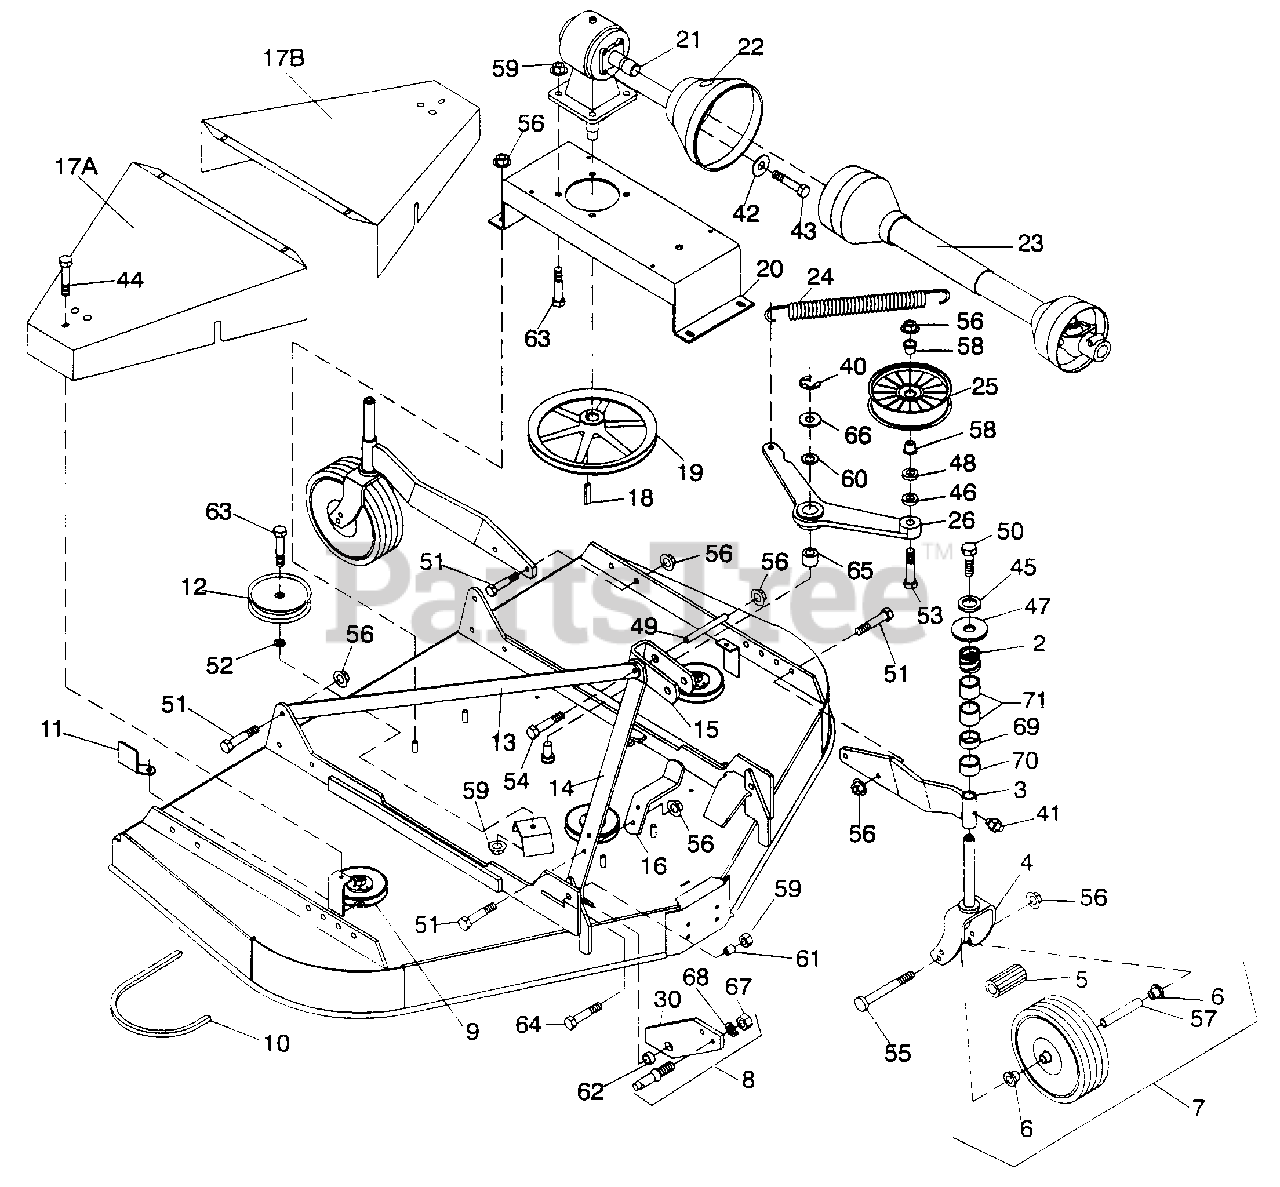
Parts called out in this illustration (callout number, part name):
2	Compression spring
3	Caster arm assembly - Right
3	Caster arm assembly - Left
4	Model 483 Caster shaft and yoke assembly
5	Roller bearing .75 x 1.38 x 1.5
6	3/4 x 1.415 Flanged wheel bearing with groove
7	10" Heavy-duty wheel w/bearing & sleeve
8	Category 1 mounting pin with nut and lockwasher
9	CW Spindle assembly
10	V-Belt
11	Belt guide, 8 GA formed
12	Flat idler, 5.5" Dia.
13	Offset link
14	Offset link
15	U-Link, .38 x 2.5 x 7.13
16	PTO Hanger bracket
17A	Right belt shield
17B	Left belt shield
18	1/4 x 1/4 x 1-1/4 HT Key
19	12.4 PD Sheave
20	Gearbox stand
21	1:1.92 Gearbox
22	Counter cone shield
23	Drive assembly complete 40, 29.1 x 45.1
24	Extension spring
25	Model 483 Idler and bearing
26	Idler arm assembly
30	Hitch plate
40	.050 x .75 External retainer ring
41	1/4-28 Grease fitting
42	5/16 Flat washer
43	8mm x 1.25P x 16mm Hexhead cap screw CL8.8
44	Whiz bolt, .375-16 x 1 flanged
45	1/2 Lockwasher
46	1/2 x 1-3/8 x 3/8 Flat washer
47	1/2 x 10GA Washer
48	.50 x 18GA Shim washer
49	1/2 x 2.75 pipe
50	1/2 NC x 1-1/4 Hex head cap screw GR5
51	1/2 NC x 1-3/4 Hex head cap screw GR5
52	5/8 x 7 GA Flat washer
53	1/2 NC x 2-1/2 Hex head cap screw GR5
54	1/2 NC x 4-3/4 Hex head cap screw GR5
55	1/2 x 5 Hex head cap screw GR5
56	1/2 NC Flanged locknut
57	1/2 x 3/4 x 3-3/8 Sleeve
58	.51 x .67 x .36 Flanged sleeve
59	5/8 NC Flanged locknut
60	5/8 x 1 x 1/4 Felt seal
61	5/8 x 1 x 7/16 HT Sleeve
62	5/8 x 1 x 9/16 HT Sleeve
63	5/8 x 1-3/4 Flanged hex head cap screw
64	5/8 NC x 3 Hex head cap screw GR5
65	3/4 x 1 x 1 Oilite bushing
66	3/4 x 16GA Flat washer
67	7/8 NF Hex nut
68	7/8 Lockwasher
69	1" x .75 pipe
70	1-1/4" x .50 Pipe
71	1" x 1.00 pipe
